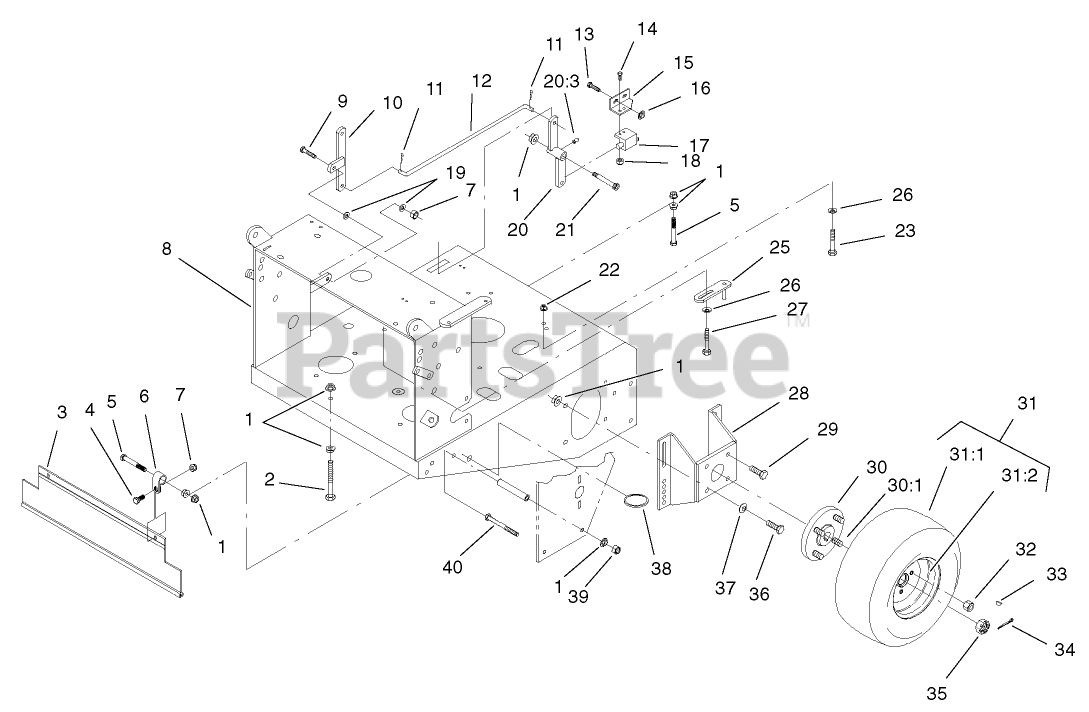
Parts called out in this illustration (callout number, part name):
1	NUT-HHF, WHIZ
2	SCREW-HH
3	Shield-Drag
4	SCREW-HH
5	SCREW-HH
6	Clip-Loom
7	NUT-LOCK, NI
8	Deck-Rear
9	SCREW-HH
10	BELLCRANK ASM
11	PIN-COTTER
12	Linkage-Engage, Blade
13	SCREW-HH
14	SCREW-PPH
15	Bracket-Switch, Blade
16	NUT-HF
17	SWITCH-OPEN, NORMALLY
18	NUT-LOCK, NI
19	WASHER-PLAIN
20	Bellcrank ASM
20:3	FITTING-GREASE, 90 DEG
22	NUT-HF
23	SCREW-HH
25	GUIDE-BELT
26	WASHER-SPRING
27	SCREW-HH
28	Mount-Motor
29	SCREW-HHF
30	HUB ASM W/STUDS
30:1	STUD-WHEEL
31	Wheel And Tire ASM
31:1	Tire-Turfmaster
31:2	Wheel-Rim
32	NUT-LUG
33	Key-Woodruff
34	PIN-COTTER
35	Nut-Slotted
36	SCREW-HH
37	WASHER-BELLEVILLE
38	Ring-Split
39	NUT-LOCK, NI
40	SCREW-HH
